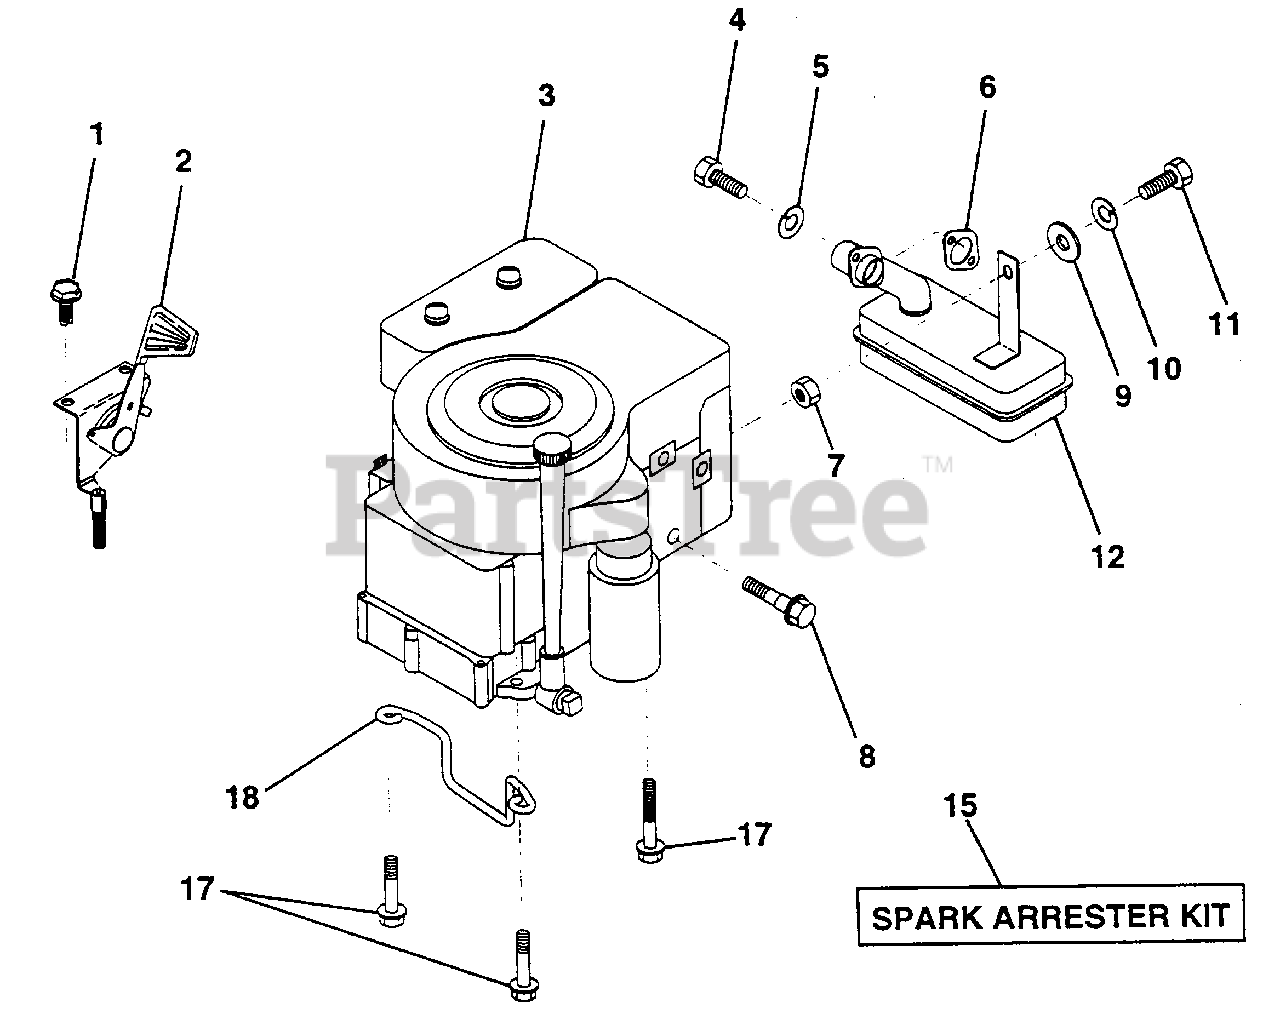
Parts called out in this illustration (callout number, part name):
1	Screw, Hex Thd. Cut 1/4-20 x 1/2
2	Control, Throttle
4	Screw, Hex, Cap 5/16-18 x 3/4
5	Washer, Lock Heavy Helical Spring 5/16
6	Gasket, Exhaust
7	Nut, Hex 5/16-18
8	Bolt, Shoulder 5/16
9	Washer 5/16 x 3/4 x 16
10	Washer, Lock Heavy Helical Spring 1/4
11	Bolt, Hex Fin 1/4-20 UNC x 1
15	Arrester, Spark (Optional equipment)
17	Screw, Hex Wsh Hd Thdrol 3/8-16 x 1-1/2
18	Keeper, Ground Drive Belt
